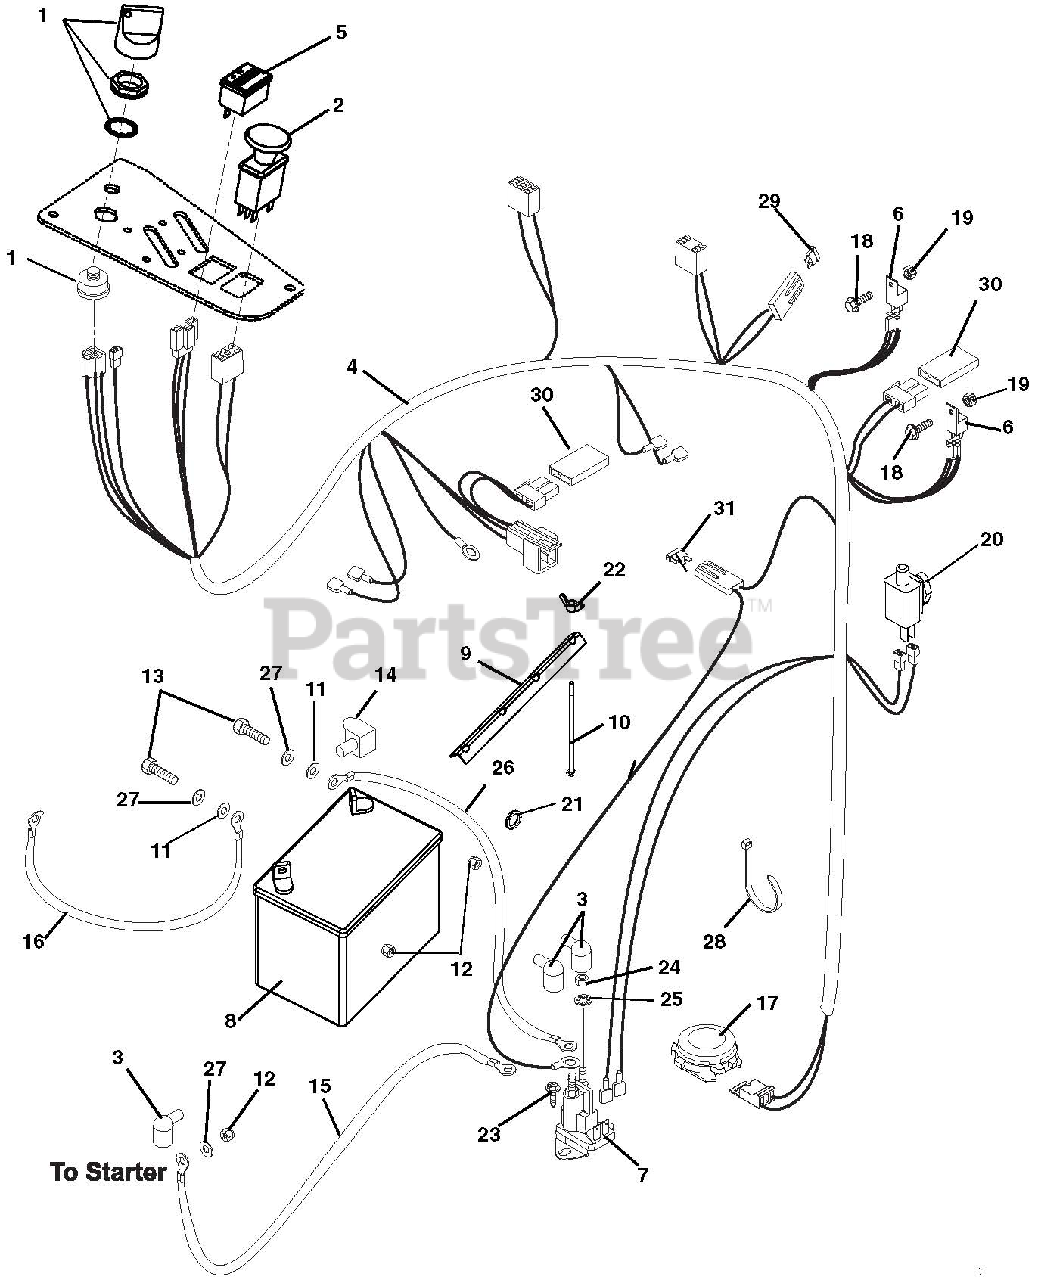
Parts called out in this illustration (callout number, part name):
1	SWITCH, IGNITION
2	SWITCH, CLUTCH
3	BOOT, EYELET TERMINAL
4	HARNESS - CZ REMOTE SOL.
5	HOUR METER - DIGITAL
6	RELAY,SEALED W/DIODE
7	SOLENOID, HP RTV
8	BATTERY, 300 CCA 10U1L
9	HOLD DOWN
10	BLT-RDHDSQNK .25-20X7.50 GR2YZ
11	@WSHR-FL-STL.281X.62X.065 YWZC
12	@NUT-HEX .25-20 YWZC
13	@BLT-HEX .25-20X.75 GR5 YWZC
14	INSULATOR
15	CABLE-POSITIVE BATTERY 9.00"
16	CABLE-NEGATIVE BATTERY 24.00"
17	SWITCH- SEAT
18	@SCR-MCH 10-24X.50 HWH YWZC
19	@NUT-LK-NYL 10-24 W/INSRT YWZC
20	SWITCH, SINGLE POLE N.O.
21	GROMMET, 2.12" ID BUNA-N
22	NUT-LK WING .250-20 YWZC
23	@SCR-TAP .25-20X.50 HWH TR YWZ
24	NUT-JAM .31-24 YWZC
25	@WSHR-LK .31X.078 REG YWZC
26	CABLE, STARTER .31X23.00X.31
27	@WSHR-LK .25X.062 REG YWZC
28	CABLE TIE LG 5-1/2
29	FUSE 20AMP
30	DIODE, CONNECTOR SHELL
31	FUSE-25 AMP ATC TYPE
